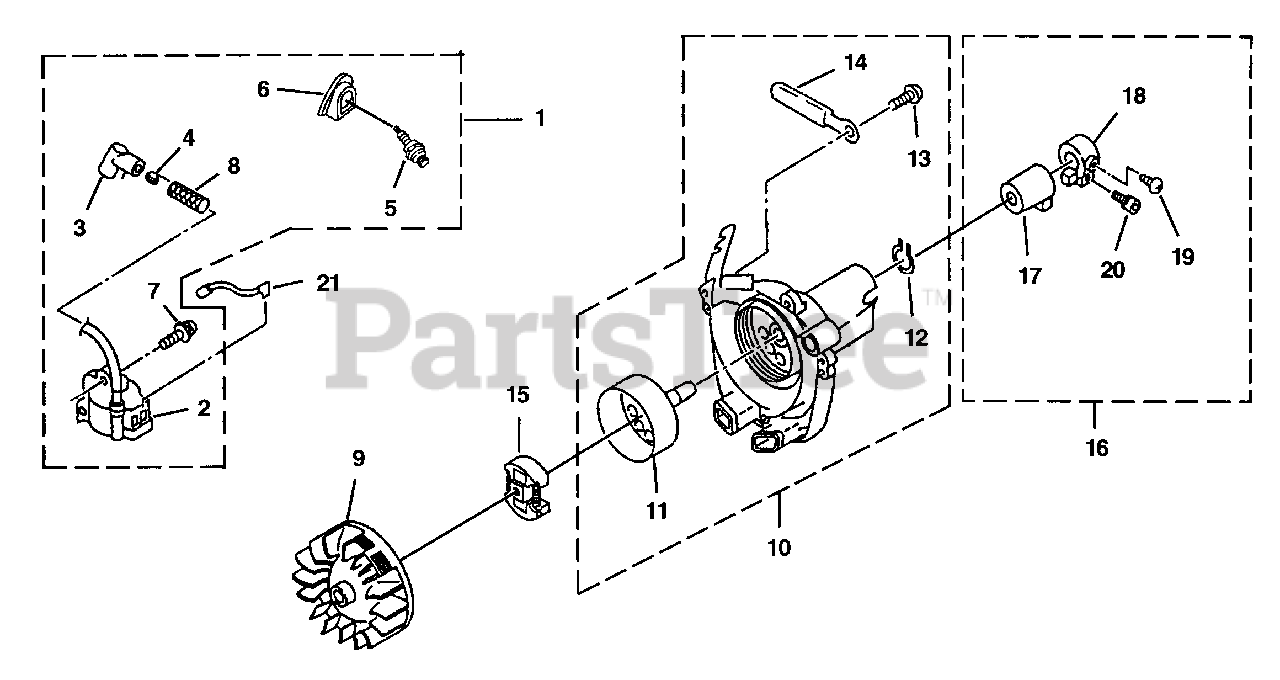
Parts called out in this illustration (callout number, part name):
1	IGNITION KIT
2	MODULE-Ignition
3	CAP-Plug
4	SPRING-Plug Cap
5	SPARK PLUG
6	COVER-Plug Cap
7	SCREW (M4 x 20 W SW)
10	CLUTCH HOUSING
11	CLUTCH DRUM
12	SNAP RING-Outer
13	SCREW-Self Tapping
14	CLAMP-Wire
16	DRIVESHAFT ISOLATOR
17	ISOLATOR
18	BRACKET-Isolator
19	SCREW-Self Tapping (M5 x 14)
20	SCREW-Socket Hd (M5 x 25)
